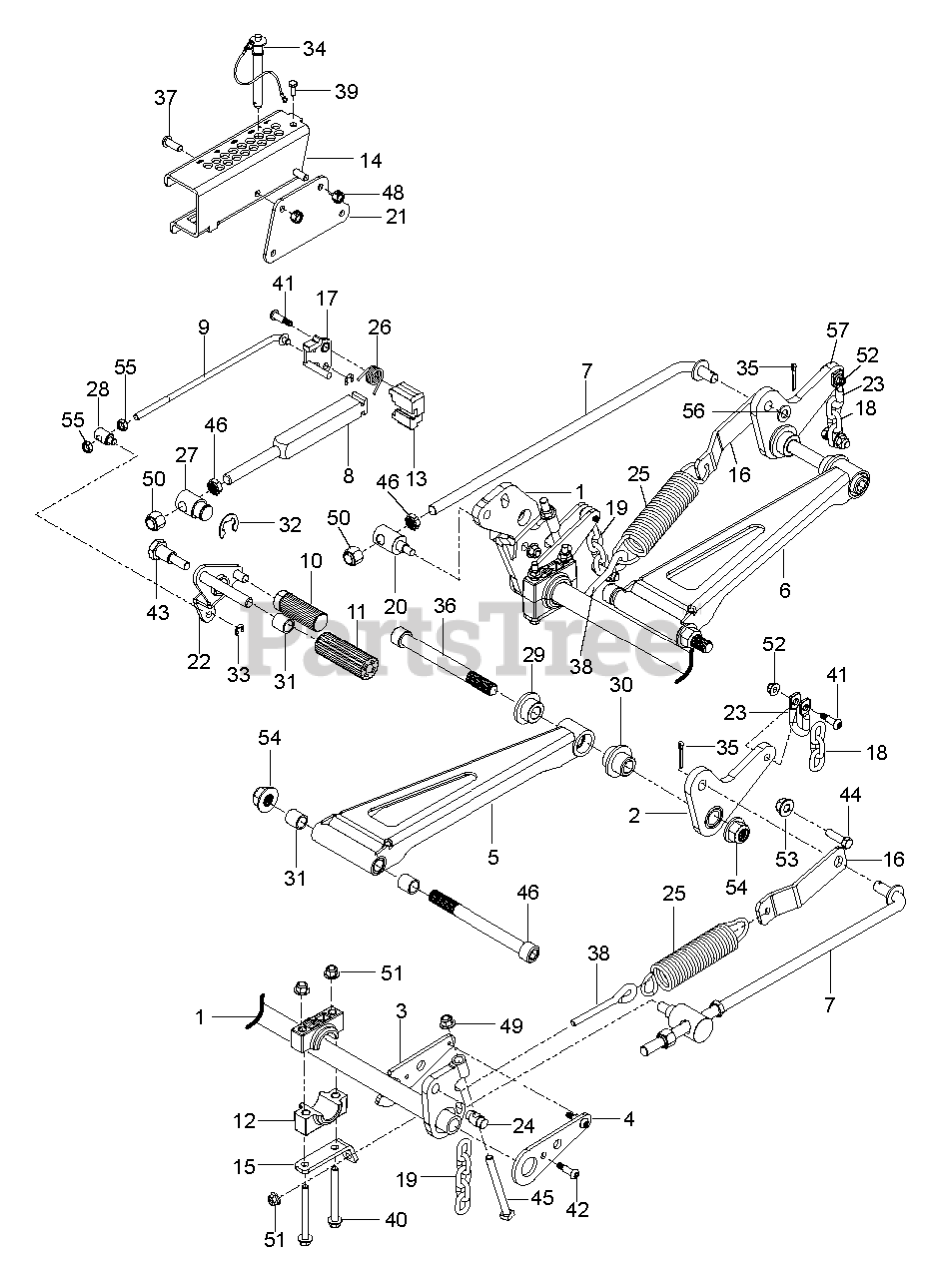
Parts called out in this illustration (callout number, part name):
1	SHAFT.WLDMNT.FRNT.DECK.LFT.PNT
2	KIT.ARM.BELLCRANK/BUSHINGS.RT
3	ARM.DECK.LIFT.INNER.BLACK
4	ARM.LIFT.DECK.OUTER.POWER.BLK
5	ARM.DRAWBAR.LH
6	ARM.DRAWBAR.RH
7	ROD. CONNECTING
8	ROD.HEIGHT.GAUGE
9	ROD.RELEASE.CONNECTING.TOE
10	PEDAL, DECK HEIGHT
11	PAD, FOOT PEDAL
12	BLOCK, PILLOW
13	BLOCK.ROD.END
14	BRACKET.ADJUSTMENT.HEIGHT.ORNG
15	BRACKET.PILLOW.BLOCK.PNT.BLACK
16	BRACKET.SPRING.ATTACH.PNT
17	KIT.LEVER.LOCK.W/BUSHING
18	LIFT CHAIN - 3 LINK
19	LIFT CHAIN
20	PIVOT.CONNECTING.ROD
21	PLATE.HEIGHT.GAUGE.MOUNT.PNT
22	LEVER ASSY TOE RELEASE
23	SHACKLE.CHAIN
24	SHAFT.TRUNNION.ATTACH
25	SPRING.LIFT.DECK.EXTNSN.PZ/PZT
26	SPRING.TORSION.RELEASE.LEVER
27	SWIVEL.HEIGHT.BAR
28	SWIVEL.TOP.RELEASE
29	BUSHING.DECK.INNER
30	BUSHING.DECK.OUTER
31	BUSHING, SLEEVE 3/4 X 1.0
32	E-RING 1"
33	E RING 3/8"
34	PIN.PUSH.BUTTON.DETENT..5X3.5
35	COTTER PIN 1/8 X 2
36	SCREW.SOCKET.HEADCP.3/4-10X7.5
37	SCREW.BUTTON.HEAD.CAP.3/8-16X1
38	EYE BOLT, 3/8 X 4"
39	SCR 5/16-18 X 1/2 SELFTAP ZN
40	SCREW.HHFS3/8-16X3.75.GR8
41	SCREW.SHOULDER.375X875.5/16-18
42	SCREW.SHLDR..375.5/16-18.88.LG
43	BOLT, SHOULDER
44	HCS 7/16C X 1 1/2
45	SCREW.HHC.7/16-14 X 4.50
46	NUT.HH.THIN.NYL.5/8-11 GR5
48	NUT 3/8C CENTERBLOCK
49	7/16-14 HEX NUT W/NYL RING ZD
50	NUT 5/8-11 NYLOC
51	NUT 3/8-16 HEX FLG NYLOC ZD
52	5/16-18 NYLOC FLANGE NUT
53	NUT 7/16-14 HEX WHIZ LK
54	NUT.HEX.FLANGED.3/4-10.NYLOK
55	NUT 3/8-24 JAM
57	KIT.ARM.BELLCRANK/BUSHINGS.LT
